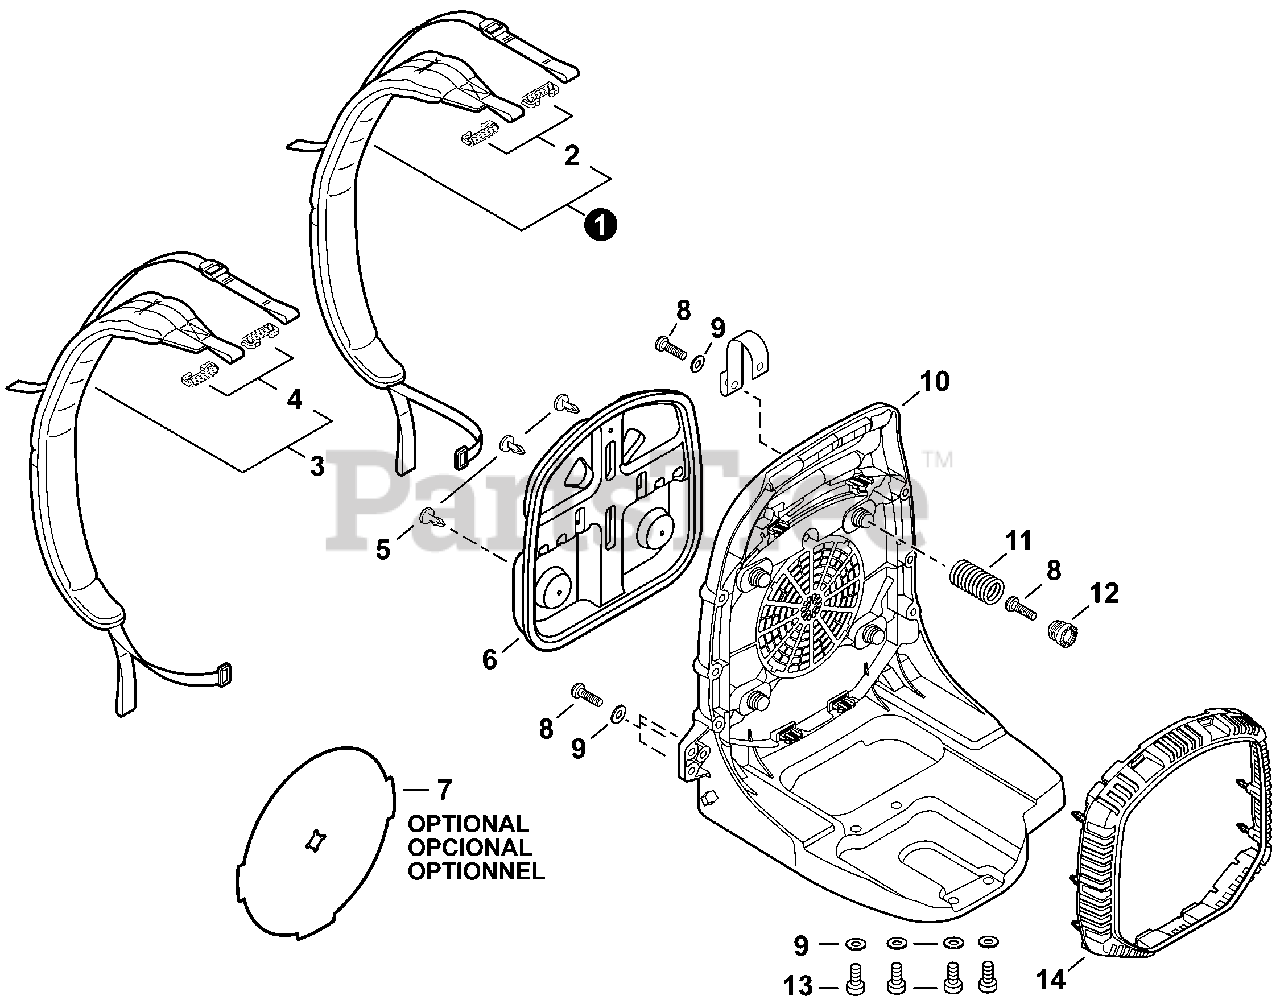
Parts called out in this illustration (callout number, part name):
1	HARNESS ASSY, RIGHT
3	HARNESS ASSY, LEFT
6	CUSHION, BACKPACK
7	INSERT, COLD WEATHER
8	BOLT, TORX 5×20
9	WASHER 5.5×16×2T
10	FRAME, BACKPACK
11	SPRING, COMPRESSION
12	HOLDER, SPRING
13	BOLT, TORX 5×20
14	GUARD, DEBRIS
